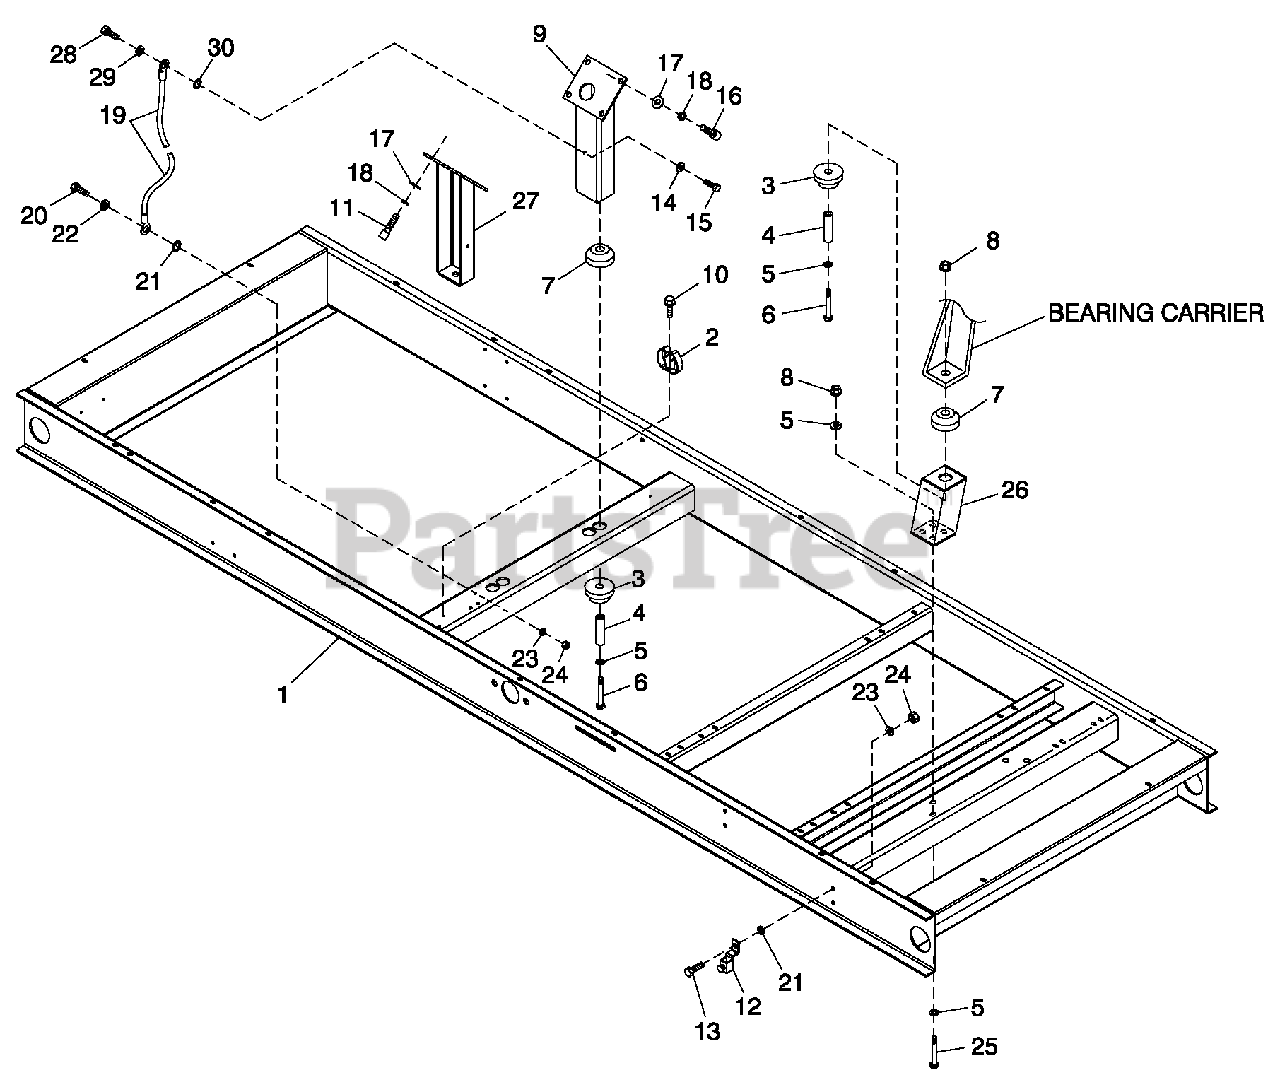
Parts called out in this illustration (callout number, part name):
1	BASECPL100-130KW6.8LGB
2	SPRING CLIP HOLDER .37-.62
3	DAMPENER VIBRATION
4	SPACER .49 X .62 X 1.87 PWDR/ZINC
5	WASHER FLAT M12
6	SCREW HHC M12-1.75 X 85 G8.8
7	DAMPENER VIBRATION 50 WHITE
8	NUT LOCKING M12-1.75
9	SUPPORT ENG 5.4L LH/RH 6.8L RH
10	SCREW HHTT M4-0.7 X 8 BP
11	SCREW SHC M10-1.5 X 60 G12.9
12	LUG SOLDERLESS 3/0-#4 X 13/32 CU
13	SCREW HHC M8-1.25X 25 G8.8
14	WASHER FLAT 1/4-M6 ZINC
15	NUT HEX M6X 1.0 G8YEL CHR
16	SCREW SHC M10-1.5 X 30 G12.9
17	WASHER FLAT 3/8-M10 ZINC
18	WASHER LOCK M10
19	ASSY WIRE 14.00"
20	SCREW HHC M8-1.25X 30 G8.8
21	WASHER SHAKEPROOFINT 3/8
22	WASHER LOCK M8-5/16
23	WASHER FLAT 5/16-M8 ZINC
24	NUT HEX M8-1.25 G8YEL CHR
25	SCREW HHC M12-1.75 X 40 G8.8
26	TOWER GBCOMPROD C5
27	SUPPORT ENGINE 6.8L LH SIDE
28	SCREW HHC M6-1.0 X 30 G8.8
29	WASHER LOCK M6-1/4
30	WASHER SHAKEPROOF INT 1/4
